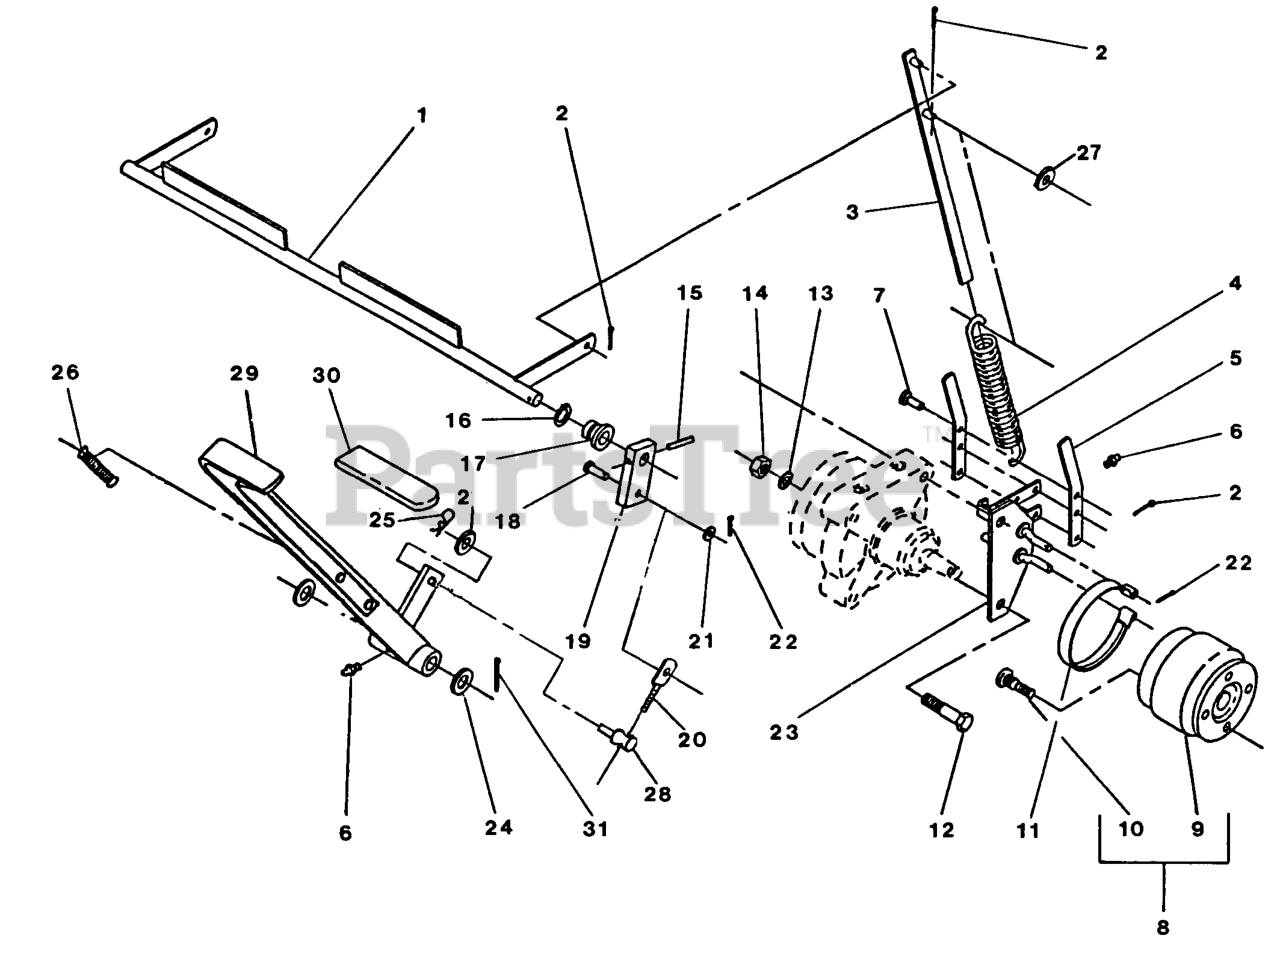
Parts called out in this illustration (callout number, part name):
1	WLD,ROD LOCKOUT
4	SPRING,EXTENSION
5	LINK,BRAKE CONNECTING
8	HUB/BRAKE DRUM ASSY
10	BOLT,HUB
11	BAND,BRAKE
18	PIN-CLEVIS
23	BRAKE BRACKET W/ZERK LH
25	PIN-COTTER
26	SPRING,BRAKE HANDLE
29	HANDLE & TRIGGER, BRAKE
30	GRIP-LEVER
